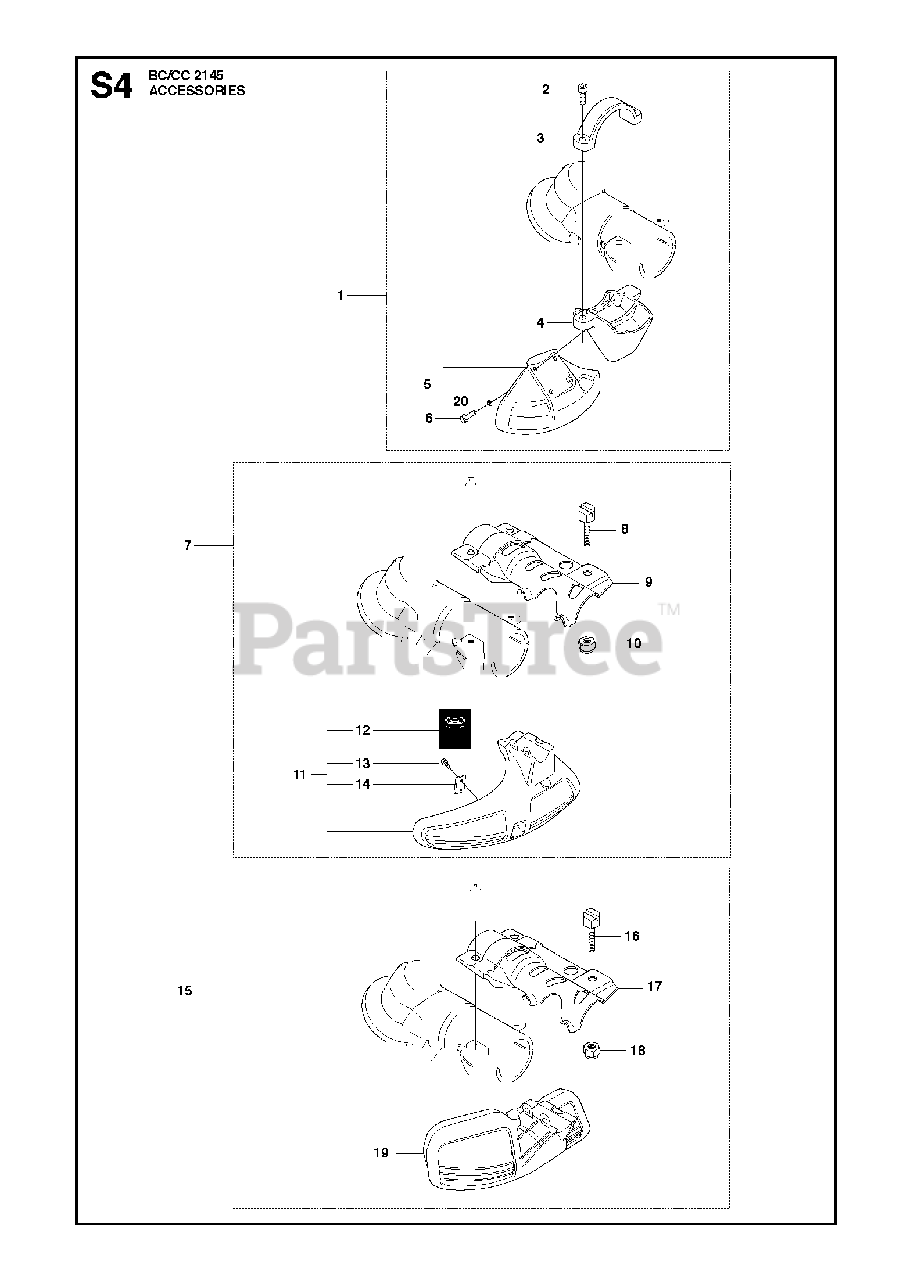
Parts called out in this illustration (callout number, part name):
1	TRIMMER GUARD ASSY
4	ADAPTER
5	RP BLADE GUARD
6	SCREW
7	SPLASH GUARD KIT
8	SCREW
9	PLATE
10	LOCKNUT M6
12	DECAL
13	SCREW
14	BLADE
15	TRIMMER GUARD ASSY
16	SCREW
17	PLATE
18	LOCKNUT M6
19	PROTCTOR
20	LOCKING NUT
